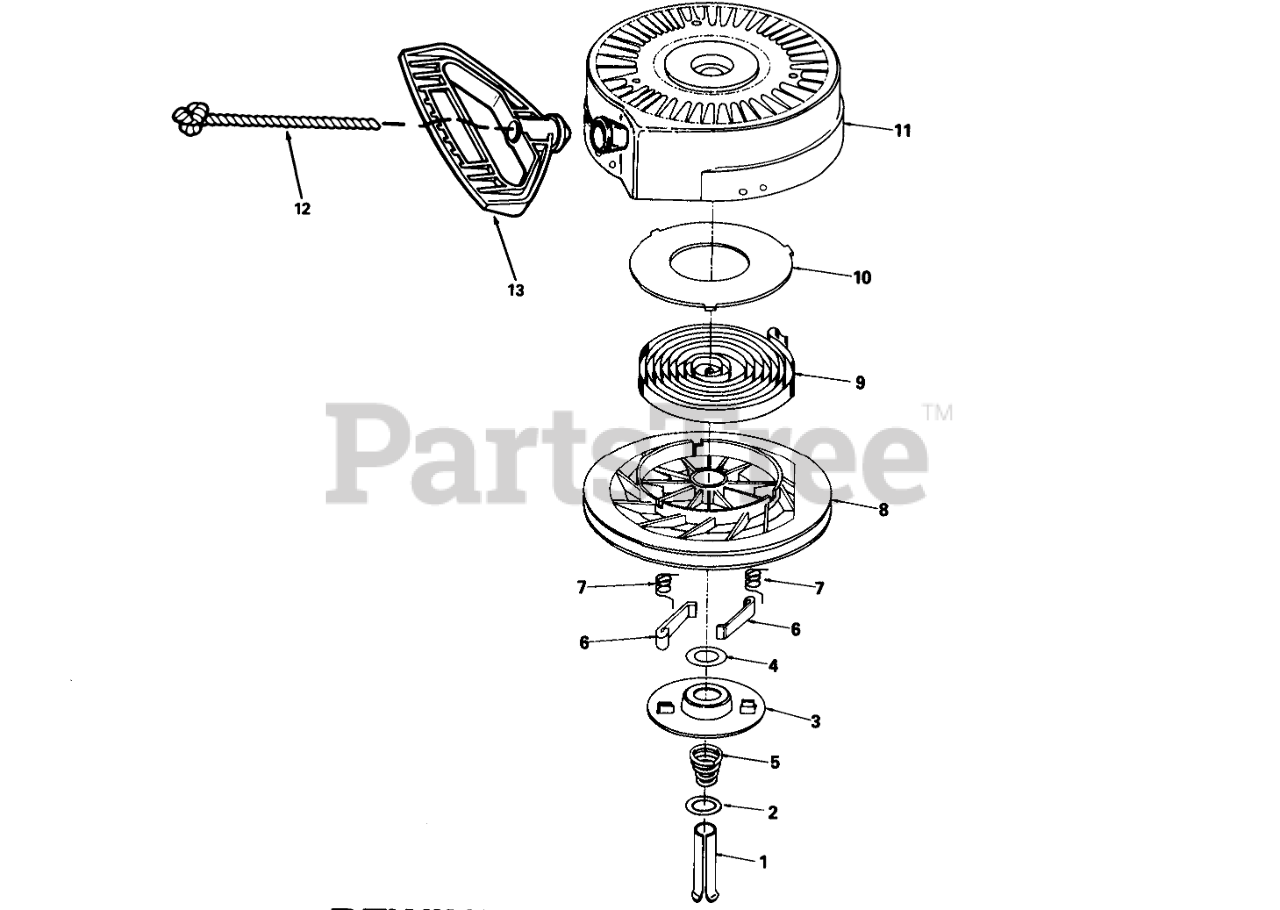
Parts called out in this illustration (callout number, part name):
1	Pin-Spring (Incl. Ref. #4)
3	Retainer
5	Brake Spring
6	Dog-Starter
7	Spring-Dog
8	Pulley
9	Rewind Spring
10	Cover-Spring
11	Housing Assembly
12	Rope-Starter (98 cut to length)
13	Handle-Starter, Mitten Grip
